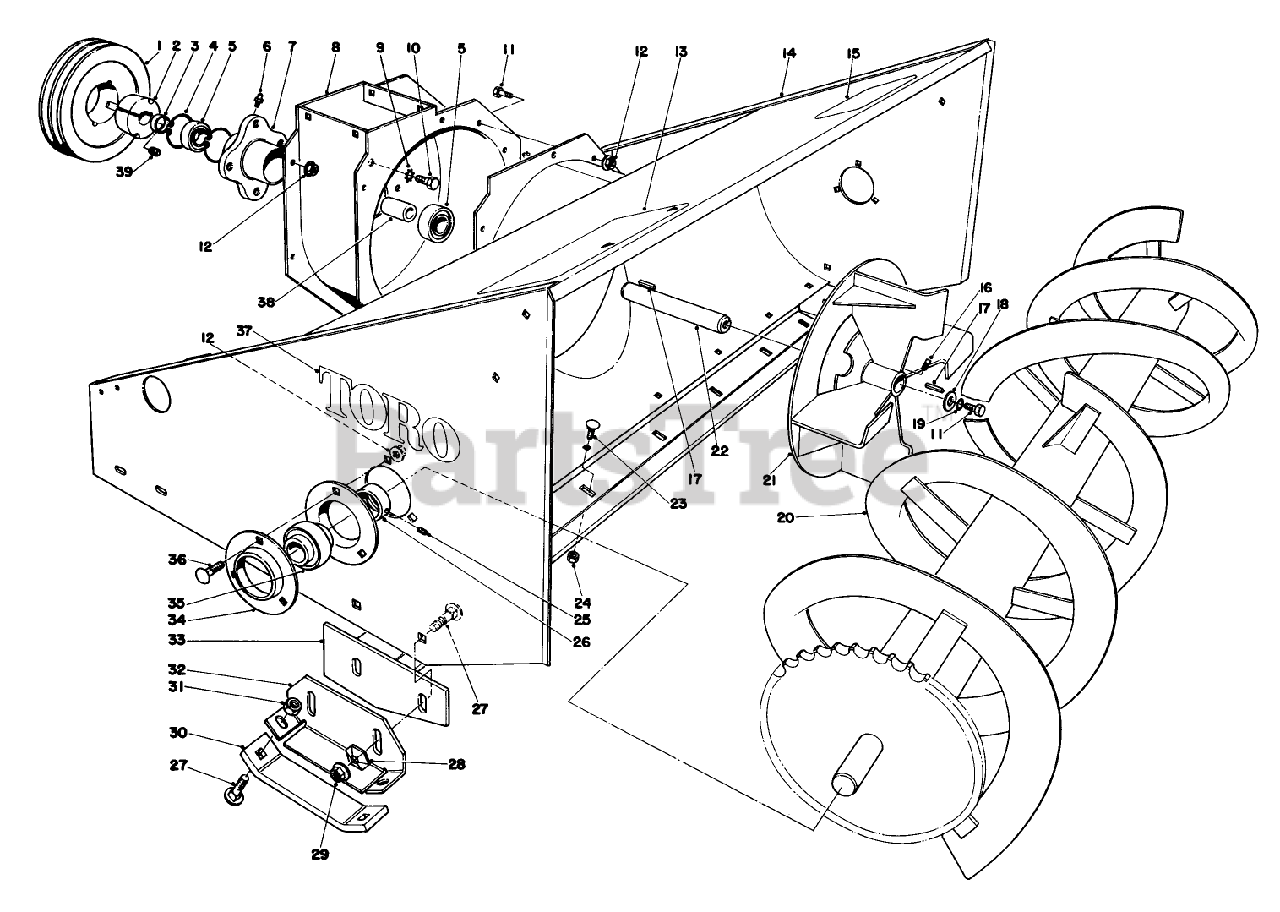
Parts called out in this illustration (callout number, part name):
1	TAPERLOCK PULLEY
2	Taper Lock Bushing (Incl. Ref. #39)
3	SPACER
4	RETAINING RING
5	BEARING
6	FITTING-LUBE, 45 DEG
7	Housing Spindle
8	BLOWER HSG WA
9	WASHER-LOCK, EXT
10	SCREW-HH
11	SCREW-HH
12	NUT-HF
13	Decal-Rear Weight
14	Auger Housing
15	Decal-Warning
16	SCREW-SET
17	Square Key
18	WASHER
19	WASHER-LOCK
20	Auger
21	IMPELLER WA 60096
22	IMPELLER SHAFT
23	SCREW-CARR
24	NUT-LOCK, NI
25	SCREW-SET, HSH
26	COLLAR-LOCK, BEARING
27	BOLT-CARR
28	LOCKWASHER-PYRAMID
29	FLANGE NUT W/LG FLG
30	SKID SHOE R
31	NUT-LOCK, CONE
32	SKID MTG PLT
33	SCRAPER WA
34	FLANGE
35	Bearing (Incl. Ref. #25 & 26)
36	SCREW-CARR
37	DECAL
38	SLEEVE 16107
39	SCREW-SET
